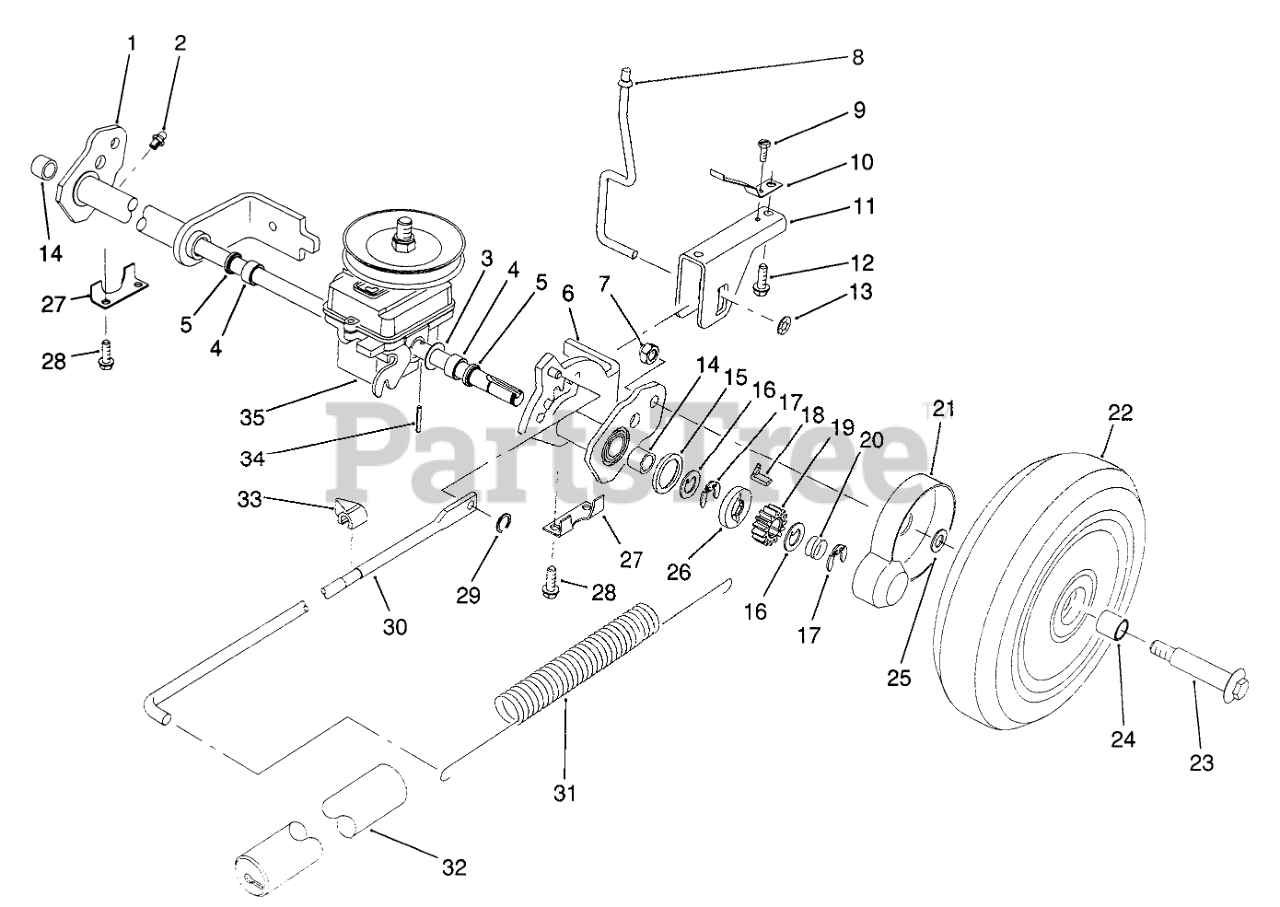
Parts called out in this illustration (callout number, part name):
1	Rear Pivot Assembly R.H. (Incl. Ref. #2, 4, 5 & 14)
2	FITTING-GREASE
3	WASHER-PLAIN
4	BUSHING
5	SEAL-OIL
6	Rear Pivot Assembly L.H. (Incl. Ref. #2, 4, 5 & 14)
7	Nut
8	TRIGGER ROD
9	SCREW 8 - 32 X 250
10	SPRING - TRIGGER RET
11	SADDLE - HOC
12	SCREW
13	PUSHNUT
14	BEARING-ROLLER
15	RING-FRICTION
16	WASHER-THRUST, KEYED
17	RING-CLIP, LOCKING
18	KEY-ROCKING, LH
19	GEAR-PINION
20	SPRING-COMPRESSION
21	COVER-WHEEL
22	Wheel, Tire & Gear Assy. (Incl. Ref. #24)
23	BOLT-WHEEL
24	BUSHING
25	SPACER-COVER, WHEEL
26	WASHER-CLUTCH
27	REAR SECURING PLATE
28	SCREW-HWHTF
29	GRIP RING
30	LINK ROD
31	SPRING-COUNTERBALANCE
32	COVER-SPRING
33	INDICATOR-HEIGHT OF CUT
34	COIL PIN
35	Gearbox Assembly
